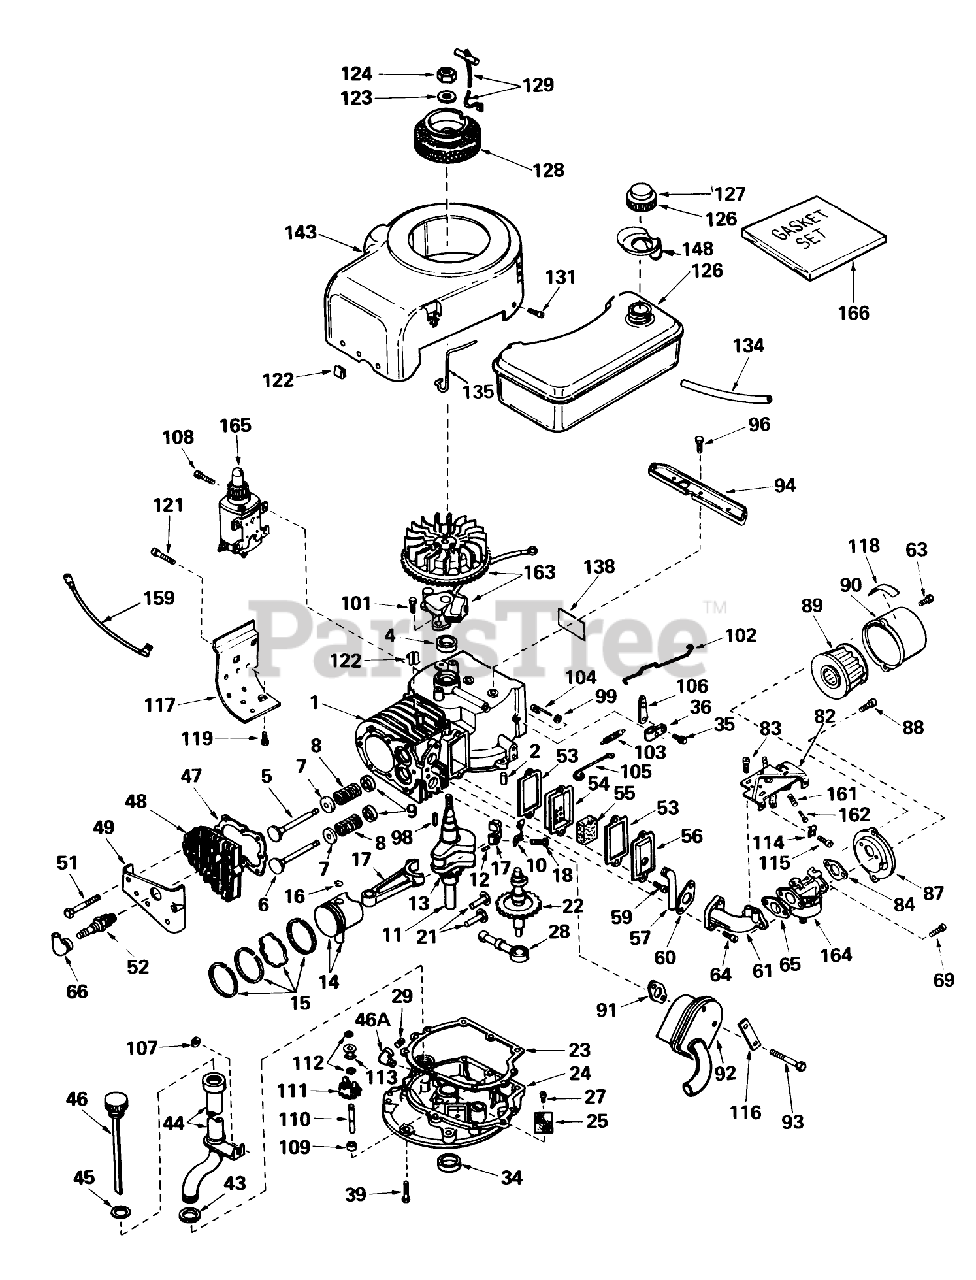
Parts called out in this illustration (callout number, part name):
1	Cylinder Assy. (Incl Nos. 2 4)
2	Pin-Dowel
4	Oil Seal
5	Valve, Intake (Standard)(Incl. No. 9)
5	Valve, Intake (1/32" oversize)(Incl. No. 9)
6	Valve, Exhaust (Standard)(Incl. No. 9)
6	Valve, Exhaust (1/32" oversize)(Incl. No. 9)
7	Cap-Spring, Valve
8	Spring-Valve
9	Keeper-Spring, Valve
10	Plate, Lock
11	Crankshaft Assy. (Incl. Nos. 12 13)
12	Pin, Groove
13	Gear-Crankshaft
14	Piston Pin Assy. (Incl. 2 of No. 16)(Standard)
14	Piston Pin Assy. (Incl. 2 of No. 16)(.010 oversize)
14	Piston Pin Assy. (Incl. 2 of No. 16)(.020 oversize)
15	ORing
15	Ring Set (.010" OS)
15	Ring Set (.020" OS)
17	Rod Assy., Connecting (Incl. Nos. 10 18)
18	Screw, Hex Hd.
21	Lifter Valve
22	Screw
23	Gasket-Cover, Cylinder
24	Flange Assy., Mounting (Incl. Nos. 25, 27, 29, 34 110)
25	Screen-Oil Filter
27	Screw
28	Pump, Oil
29	Plug-Drain, Oil (SQH 1/4-18)
34	Seal-Oil
35	Screw
36	Clamp-Lever, Governor
39	Screw (1/4-20 x 1-1/4)
43	O-Ring
44	Tube, Oil Fill
45	O-Ring
46	Plug Gauge Assy., Oil
46A	Elbow, 90
47	Gasket-Cylinder Head
48	CYLINDER HEAD
49	Cover-Head, Cylinder
51	Screw Hex Hd. Cap
52	Plug, Spark (J17LM or equiv.)
53	Gasket-Breather
54	Body-Breather
55	Element-Breather
56	Cover-Valve
57	Tube-Breather
59	Screw
60	Gasket-Intake
61	Pipe-Intake
63	Screw
64	Screw (T-30, 5/16-18x1-3/32)
65	Gasket
66	Cover-Spark Plug
69	Screw-Hex Hd.
82	Control Assy., Speed (Incl. Nos. 161 162)
83	Screw (10-24 x 9/16)
84	Gasket
87	Bracket
88	Screw (10-32 x 1/2)
89	Element
90	Body
91	Gasket Exhaust
92	Muffler
93	Screw Hex Hd.
94	Bracket-Blower Housing
96	Screw (1/4-20x19/32)
98	Key-Flywheel
99	Washer-Flat
101	Screw
102	Link Governor
103	Spring Governor
104	Rod, Governor (Incl. Nos. 146)
105	Link Governor Spring
106	Lever-Governor
107	Washer
108	Screw
109	Spacer
110	Shaft, Governor
111	Governor Gear ASM
112	Ring-Retaining
113	Spool-Governor
114	Conduit
115	Screw (10-32 x 3/8)
116	62513 SNWTHWR W/284
117	Emnsion, Blower Housing
118	Decal
119	Screw
121	Screw
122	51004 GIL ROTARY TI
123	Washer
126	Tank Assy., Fuel (Incl. No. 127)
127	Cap, Fuel
128	Hub Screen, Rope Starter
129	Rope Assy., Starter
131	Screw, Hex Hd.
134	Line-Fuel (8.62)
135	Clamp, Tank Holdown
138	480B GIL SNWTHWR O/
143	Housing Blower
148	Deflector-Fuel
159	SPOOL RETAINER (10-PK)
161	Spring-Compression
162	Screw
163	Magneto
164	Carburetor
165	Tine Shaft
166	Gasket Set
